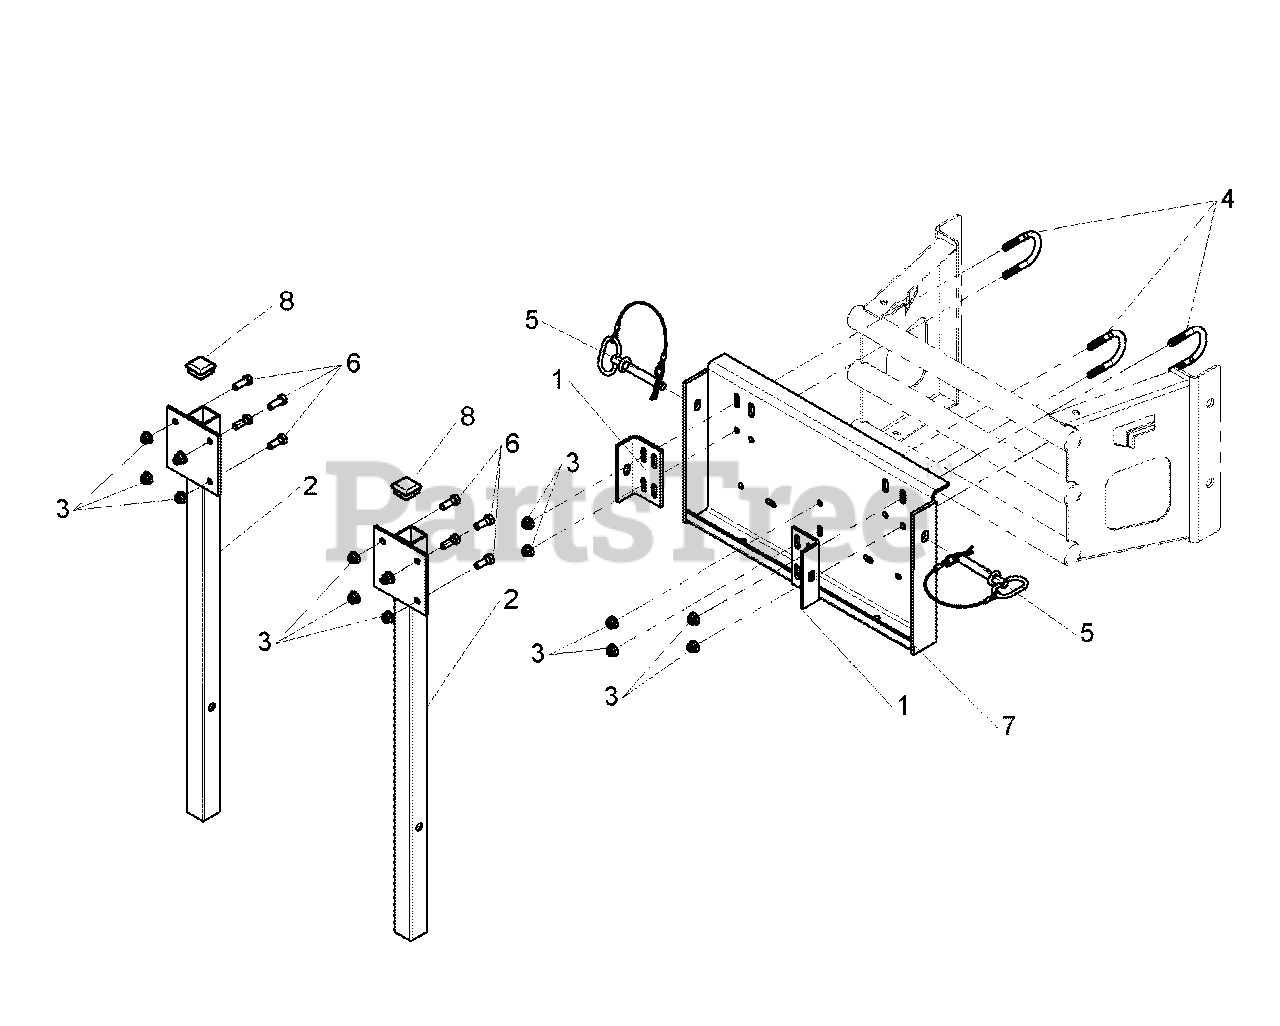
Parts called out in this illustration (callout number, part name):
1	MOUNT, TAB, BLACK
2	WELD, MOUNT, POST - BLK
3	NUT, 3/8-16 HEX NYLOCK FLANGE
4	U-BOLT, 3/8 X 1-1/4
5	PIN, HITCH, .50 X 3.25 W/ LAY
6	BOLT, 3/8-16 X 1" GD5 YZ
7	WELD, BAGGER MNT,500/1500/4500-BLK
8	CAP, PLASTIC, 1-1/2" X 1-1/2
